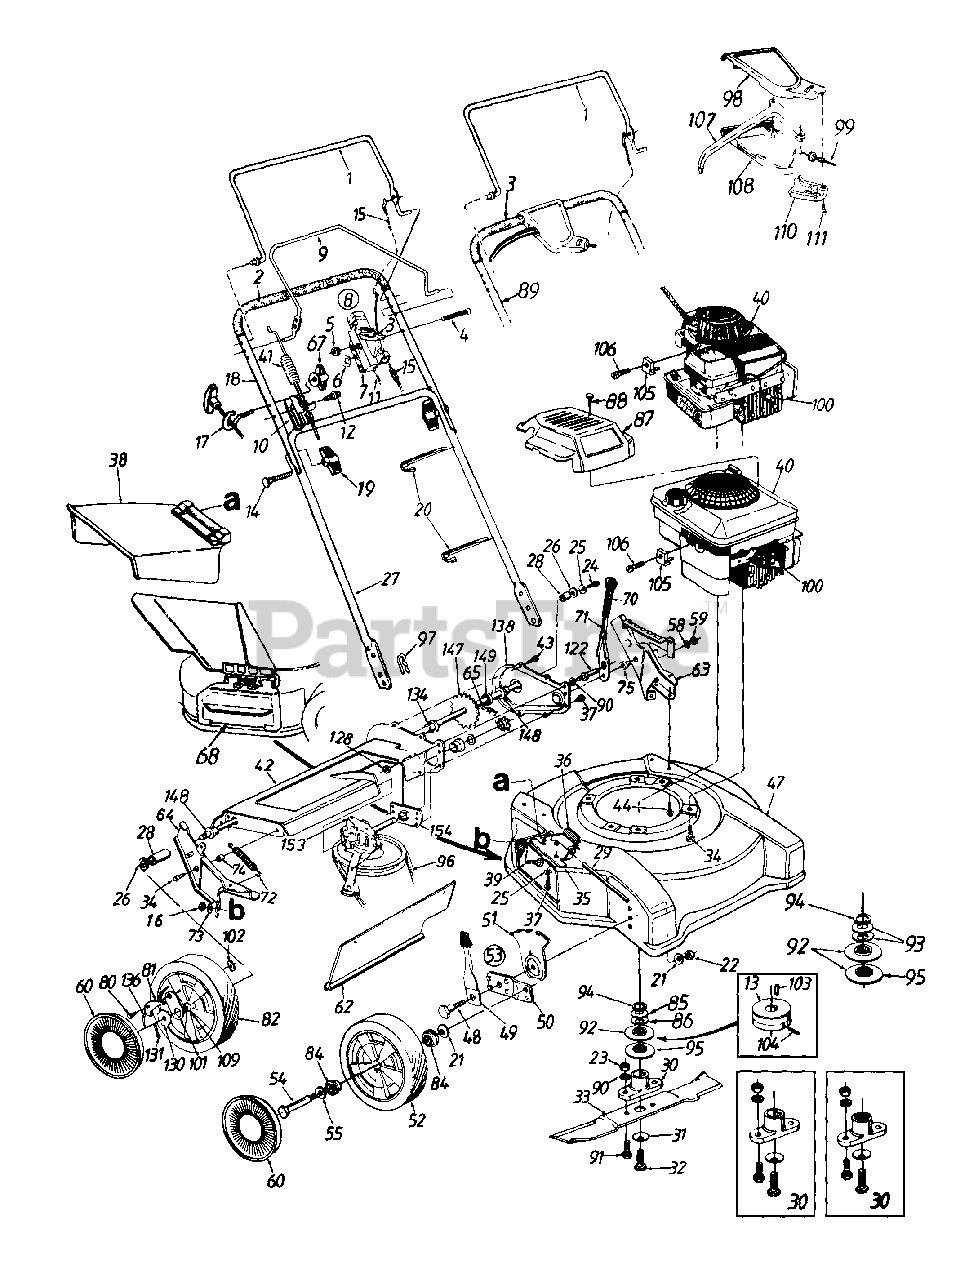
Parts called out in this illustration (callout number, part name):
2	Foam Grip
3	Throttle Lever
4	Oval C-Sunk Scr.
5	Hex L-Nut 1/4-20 Thd.
6	Spr. Wash .66" I.D.
7	Throttle Body
8	Throttle Box Comp.
11	Throttle Cable 55" Lg.(B&S)
12	Hex Wash. AB-Tap Scr. 5/16 x .75" Lg.
13	Keyed Pulley
14	Curved Hd. Bolt 5/16-18 x 2"
15	Control Cable 39" Lg.(B&S)
16	L-Wash. 5/16" I.D.
17	Rope Guide
20	Cable Tie
21	Bell-Wash .38" I.D. x .88"
22	Hex Nut 3/8-16 Thd.
23	Hex Nut 3/8-24 Thd.
24	Hex Bolt 1/4-20 x .62" Lg. (Grade 5)
25	Bell-Wash. 1/4" I.D.
26	Fl-Wash .531" I.D. x .93"
28	Spacer .513" I.D. x .703"
29	Hinge Pin
30	Blade Adapter Kit
31	Bell-Wash .39" I.D.
32	Hex Bolt 3/8-24 x 1.5" Lg.
33	22" Blade
34	Hex L-Wash. Hd. Scr. 3/8-16 x 1.0" Lg.
35	Adapter Plate
36	Torsion Spring
37	Hex Self-Tap Scr. 1/4-20 x .5"
38	Chute Deflector Ass'y.
39	Carriage Bolt 5/16-18 x .62" Lg.
40	Engine
41	Drive Cable - 41.5" Lg. (Dual Bail)
44	Hex Wash. Hd. B-Tap Scr. 5/16-18
49	Spring Lever Ass'y. w/Knob
51	Height Adj. Plate
52	Wheel Ass'y. Comp.
53	Height Adj. Ass'y. Comp.- R.H.
54	Shld. Bolt .498" Dia. x 1.45"
55	Wave Wash .51" I.D. x .78"
58	Fl-Wash .385" I.D. x .87"
59	Hex Patch L-Nut 3/8-24 Thd.
60	Hub Cap
62	Rear Flap
63	L.H. Handle Wheel Brkt. Ass'y.
64	R.H. Handle Wheel Brkt. Ass'y.
65	#48 Chain .5" Pitch x 30 Links
67	Handle Knob 1/4-20 Thd.
68	Mulching Baffle
71	Height Adj. Lever
72	Ext. Spring .5" O.D. x 3.8" Lg.
73	Bell-Wash. 5/16" I.D.
74	Spacer .383" I.D. x .503"
75	Shld. Spacer .5" Dia.
80	Shld. Scr .342" Dia. x .268"
81	Pawl
82	Wheel Ass'y. Comp.
84	Bearing
85	Spr. Wash .89" I.D. (Keyed)
86	Fl-Wash .885" I.D. (Keyed)
87	XTE Engine Shroud (Black)
88	Hi-Lo Scr. #8-18 x 1.25" Lg.
90	L-Wash. 3/8" I.D.
91	Hex Bolt 3/8-24 x 1.0" Lg.
92	Splined Pulley Half (2 Req'd.)
93	Bell-Wash. 1.01" I.D.
94	Crankshaft Spacer
95	Lower Pulley Half
96	"V"-Belt
97	Hairpin Clip
98	Control Cover - Upper Half
99	S.P. Cable (Single Bail)
100	Spark Plug Boot
101	Pawl Plate
102	Weld L-Nut 1/4-20 Thd.
103	Sq. Key 3/16" x 3/4" Lg.
105	Cable Clamp (B & S)
106	Hex Wash. Hd. Scr. #10-32 x .62" Lg. (B & S)
107	Control Lever
108	Control Cover - Lower Half
109	Sleeve Brg 1/2" I.D.
110	Mounting Cap
111	Fl-"C"-Sunk Hd. Tap Scr. 010 x .75" Lg.
122	Shld. Pin 3/8-24 x 1.43" Lg.
128	Hex Jam Nut 3/8-24 Thd.
130	Ratchet Wheel 1.62" O.D.
131	Cotter Pin 1/8" Dia.
134	Hex Flange Bearing
136	Spring - Nylon
148	Hex Flange Bearing
149	Fl-Wash.531" I.D. x .93"
153	Transmission Comp
